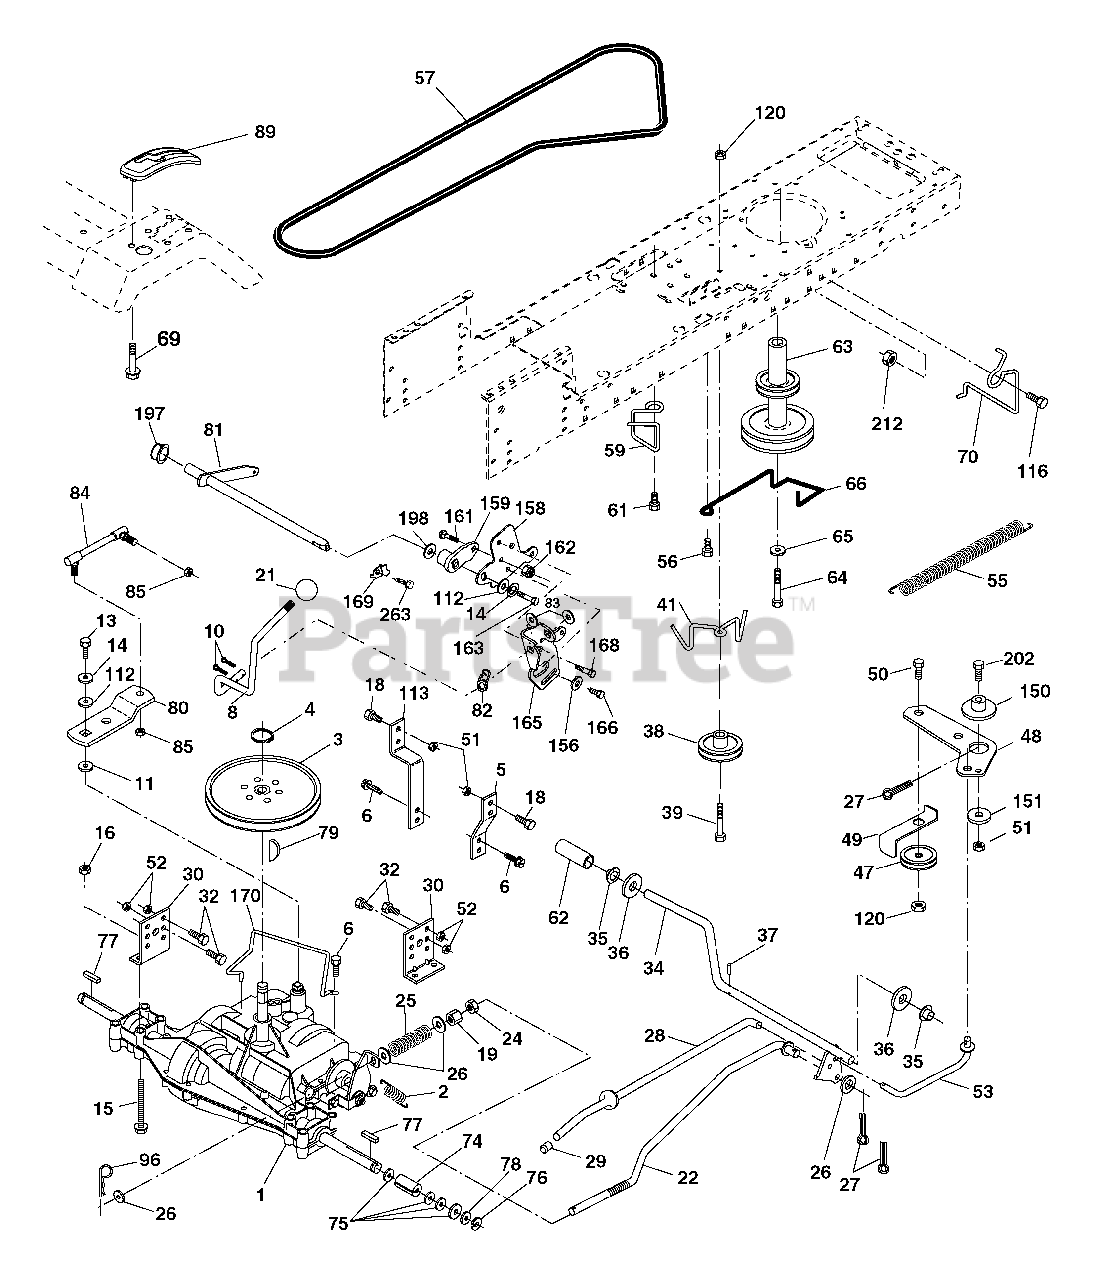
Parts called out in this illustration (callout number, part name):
2	Spring Return Brake
3	Pulley Transaxle 18"tires
4	Ring Retainer # 5100-62
5	Strap Torque 30 Degrees RH
6	Screw 5/16-18 x 3/4
8	Rod Shifter Blk
10	Pin Cotter 1/8 x 1 Cad
11	Washer Plate Shf 388 Sq Hole
13	Bolt 1/4-28 unf Gr. 8 w/Patch
14	Washer Lock Hvy Helical 1/4
15	Bolt Hex Flghd 5/16-18 Gr. 5
16	Nut 5/16-18
18	Bolt Fin Hex 3/8-16 unc x 1 Gr. 5
19	Nut lock Hex w/Ins 3/8-16 Unc
21	Knob
22	Rod Brake LT
24	Nut Hex Jam 3/8-16 unc
25	Spring Rod Brake 2 00 Zinc
26	Washer 13/32 x 13/16 x 16 Ga.
27	Pin Cotter 1/8 x 3/4 Cad
28	Rod Brake Parking LT/YT
29	Cap Brake Parking Black
30	Bracket Transmission
32	Bolt Fin Hex 5/16-18 x 3/4
34	Shaft Asm Pedal Foot Nibbed
35	Bearing Nylon Blk 629 Id
36	Washer 21/32 x 1 x 16 Ga.
37	Pin Roll 3/16 x 1"
38	Pulley Composite Flat
39	Bolt 3/8-16 x 2-3/4
41	Keeper Belt Idler
47	Pulley Idler V Groove Plastic
48	Bellcrank Clutch Grnd Drv STL
49	Retainer Belt Style Spring
50	Bolt Carr Sh 3/8-16 x 1-1/2 Gr. 5
51	Nut Crownlock 3/8-16 unc
52	Nut Crownlock 5/16-18 unc
53	Link Clutch
55	Spring Return Clutch 6 75
56	Screw 3/8-16 x 1-1/4
57	V-Belt Ground Drive 95 .25
59	Keeper Belt Chassis Span Ctr
61	Screw 3/8-16 x .875
62	Cover Pedal Blk Round
63	Engine Pulley LT/YT
64	Bolt Hex 7/16-20 x 4 Gr. 5
65	Washer Lock Hvy Hlcl Spr 7/16
66	Keeper Belt Engine
69	Screw 1/4 x 1/2 unc
70	Guide Belt Mower Drive RH
74	Spacer Axle
75	Washer 25/32 x 1 1/4 x 16 Ga.
76	E-ring #5133-75
77	Key Square 2 0 x 1845/ 1865
78	Washer 25/32 x 1-5/8 x 16 Ga.
79	Key Woodruff
80	Arm Shift Transaxle
81	Shaft Asm Cross Taper
82	Spring Torsion Shift
83	Washer 17/32 x 3/4 x 16 Ga.
84	Link Transaxle
85	Nut Lock Center 1/4-28
89	Console Shift
96	Retainer Spring 1"
112	Washer 9/32 x 3/4 x 10 Ga.
113	Strap Torque 90 Degrees LH
116	Bolt Rdhd Sq Neck 3/8-16 x 1
120	Nut Lock Flg 3/8-16
150	Spacer Retainer Lt
151	Washer 13/32 x 2 x 10 Ga.
156	Washer Srrrtd 5/16 ID x 1.0 x .125
158	Bracket Shift Mount
159	Hub Shift
161	Bolt 1/4-20 x 3/4 Gr. 5
162	Nut Crownlock 1/4-20 unc
163	Bolt Hex Fin 1/4-20 unc x 1 Gr. 5
165	Bracket Pivot Lever
166	Screw 5/16-18 x 5/8
168	Bolt Shoulder 5/16-18 x .561
169	Plate Fastening
170	Keeper, Belt Transaxle
197	Nyliner Snap-In 5/8
198	Washer Nylon
202	Bolt Carr Sh 3/8-16 x 1-3/4 Gr. 5
212	Nut Hex Flg Lock
